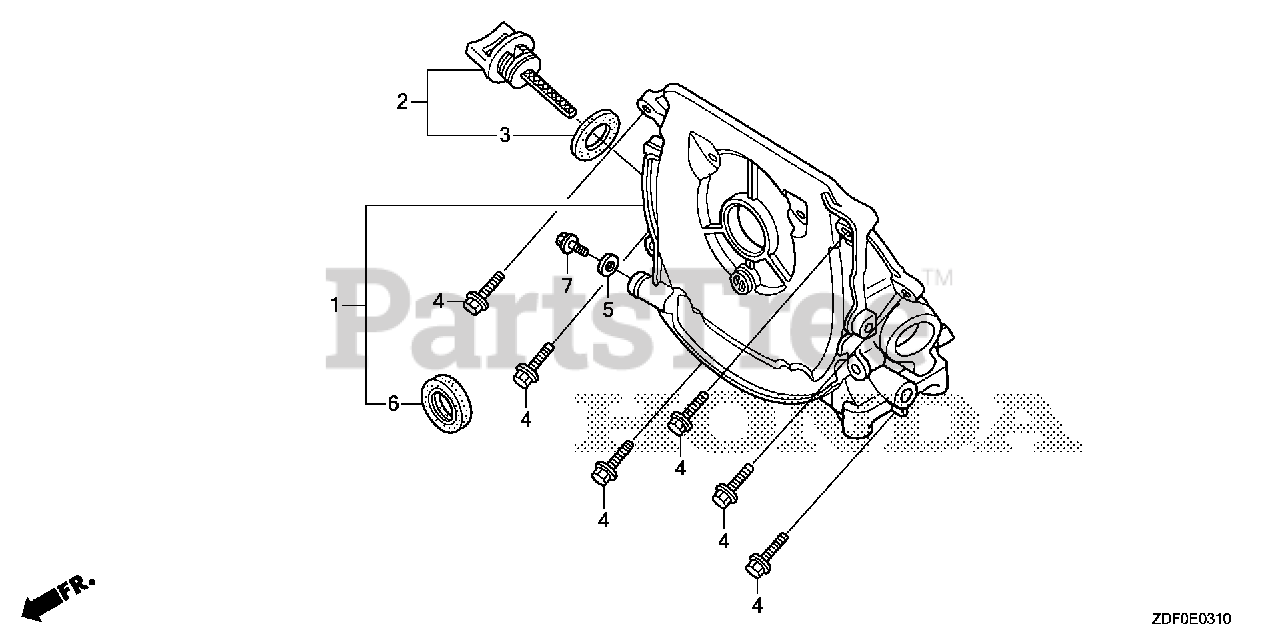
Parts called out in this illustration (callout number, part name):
1	CASE ASSY., OIL
2	CAP ASSY., OIL FILLER
3	GASKET, OIL FILLER CAP
4	BOLT, FLANGE (5X23)
5	GASKET (8MM)
6	OIL SEAL (17X27X5) (KOYO)
7	BOLT, FLANGE (8X12)
